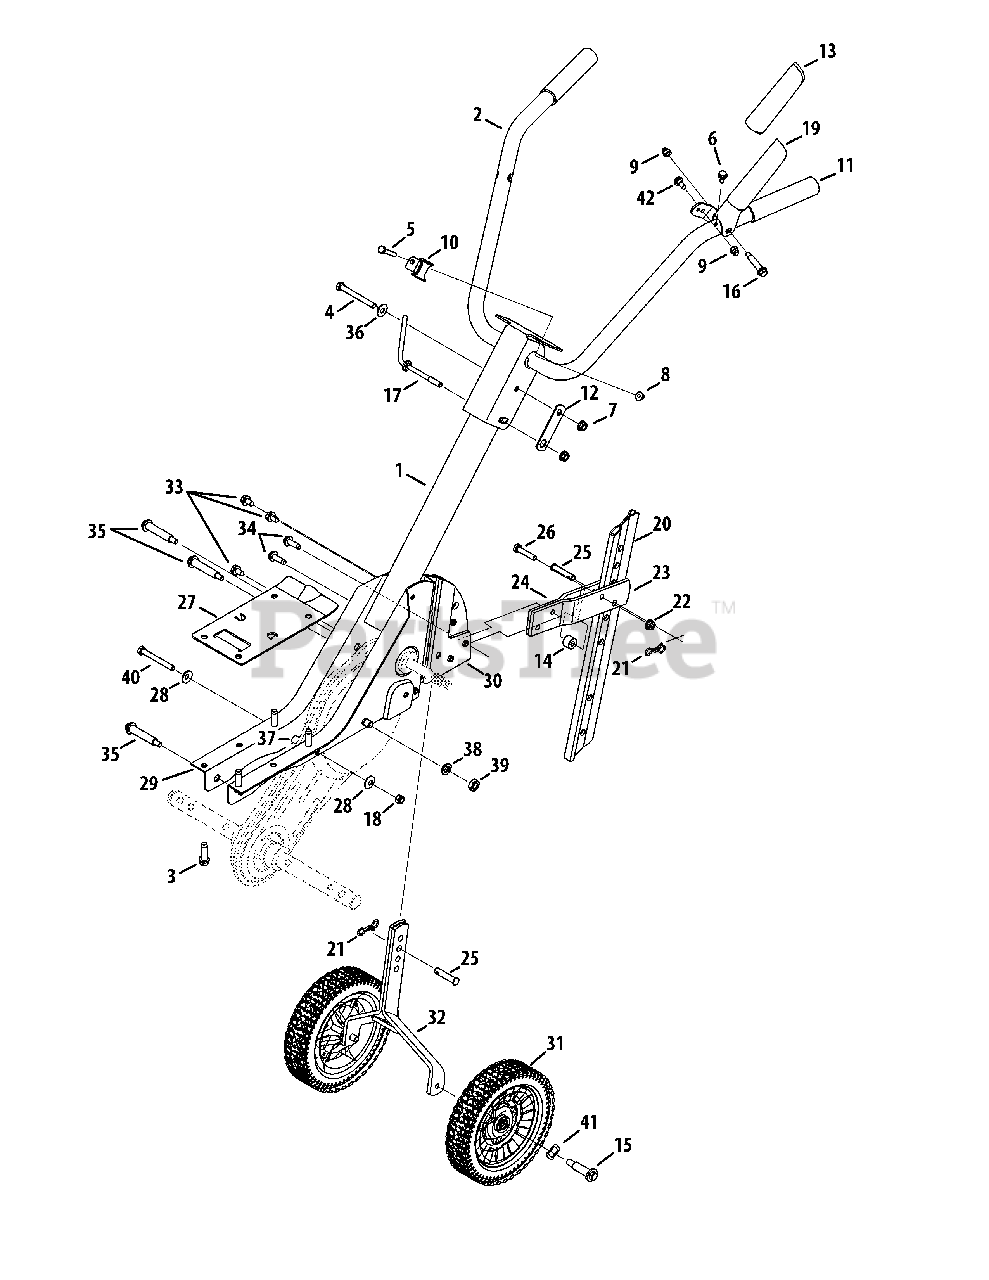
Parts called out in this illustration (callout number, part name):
1	Handle Tube Assembly
2	Handle Handle Assembly
3	Screw, 3/8-16 x 1.250
4	Hex Cap Screw, 5/16-18 x 3
5	Hex Head Screw, 1/4-20 x 1.50
6	Screw, 1/4-14 x .625
7	Hex Flange L-Nut, 5/16-18
8	Flangelock Nut, 1/4-20
9	Acorn Lock Nut, 1/4-20
10	Rope Guide
11	Grip, 1.0 x 5.0
12	Retainer Bracket
13	Grip, Handle
15	Shoulder Screw, .496 x 1.445
16	Shoulder Screw, .375 x 1.355, 1/4-20
17	Handle Adjustment Crank
18	Nylon Hex Nut, 5/16-18
19	Clutch Lever Assembly
21	Cotter Pin, Bow Tie
22	Hex Flange L-Nut, 5/16-18
23	Tail Piece Bracket, Left
24	Tail Piece Bracket, Right
25	Clevis Pin
26	Hex Bolt, 5/16-18 x 1.5"
28	Bell Washer, .340" x .872"
31	Wheel, 8 x 1.75
32	Wheel Hanger Bracket Assembly
33	Screw, Self-tapping, 5/16-18, .750,
34	Hex Washer TT-Tap Screw
35	Shoulder Bolt, 5/16-18
36	Bell Washer, .34"
38	Lock Washer, 7/16
39	Jam Nut, 7/16-20
40	Hex Cap Screw, 5/16-18 x 3
41	Wave Washer .531 x .781 x .013
42	Shoulder Screw, .3175 x .188, 1/4-20
